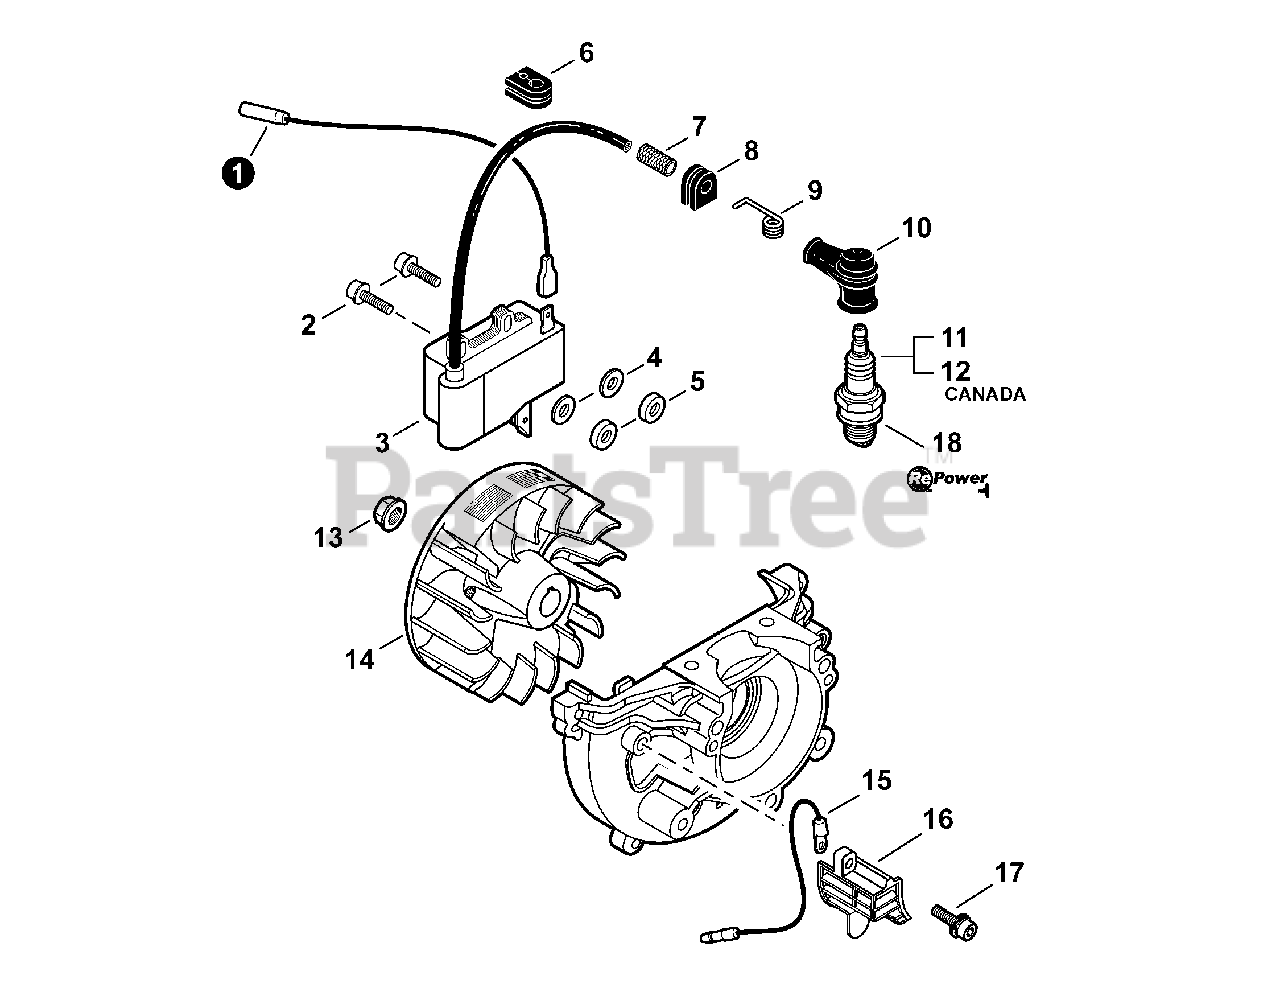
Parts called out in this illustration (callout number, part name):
1	LEAD - IGNITION
3	COIL, IGNITION
4	WASHER 4mm
5	INSULATOR 4
6	GROMMET
7	TUBE, INSULATOR
9	TERMINAL, SPARK PLUG
10	CAP, SPARK PLUG
11	SPARK PLUG - BPM-8Y
12	SPARK PLUG - BPMR-8Y
13	NUT, FLANGE M8
14	FLYWHEEL
15	LEAD - GROUND
16	COVER, DUST
17	BOLT 5×16
18	TUNE-UP KIT - REPOWER
